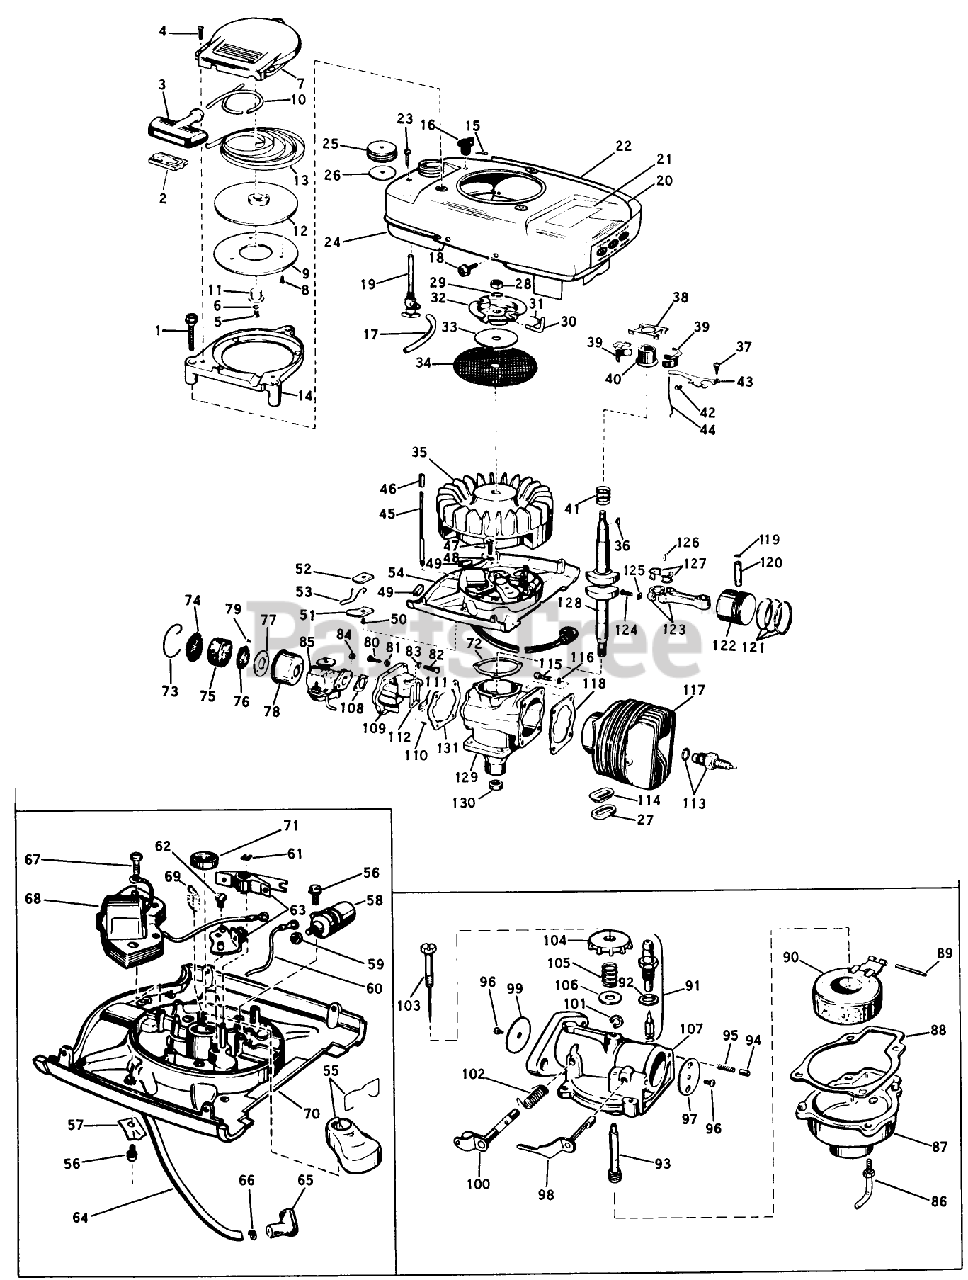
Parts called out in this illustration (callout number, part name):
9	Plate-Pulley
13	RECOIL SPRING
15	Cotter Pin-Choke Knob
16	KNOB, CHOKE BAR
18	SCREW S
19	VALVE&SCREEN SM
22	Decal-"Lawn-Boy"
25	Gas Cap
30	PIN - STARTER
40	COLLAR S
42	WEAR BLOCK S
43	GOVERNER LEVER AY
44	GOVERNOR ROD S
50	Screw Shut-off Switch
63	BREAKER AY. S
65	Cover-Rubber
72	GASKET S
75	ELEMENT
77	BACK-UP PLATE
80	SCREW S
84	STOP NUT
96	Screw-Choke Disc
98	CHOKE SHAFT&LVR AY
103	NEEDLE AY. S
105	Spring-Ndl. Adj.
108	GASKET S
111	PLATE-BACKUP, REED
113	Spark Plug
118	GASKET S
127	LINER ASM
